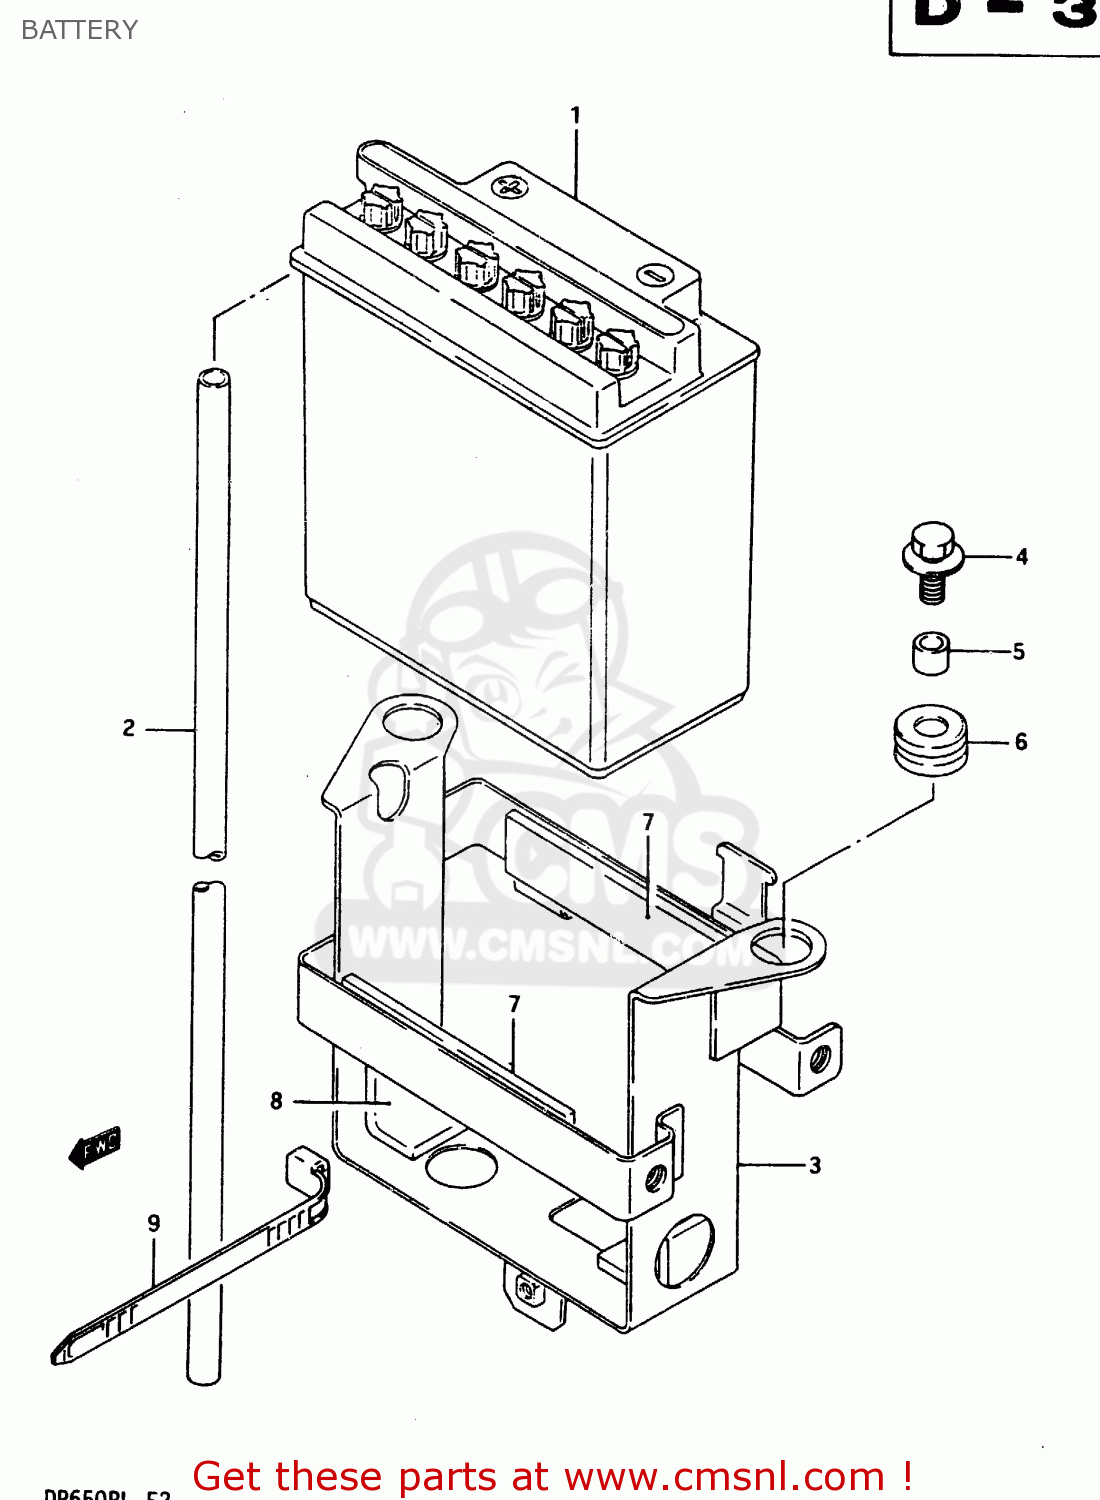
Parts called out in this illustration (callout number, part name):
1	BATTERY ASSEMBLY (12V)
2	HOSE,BATTERY EXHAUST
3	HOLDER,BATTERY
4	BOLT
5	SPACER(6.1X9X7.5)
6	CUSHION
7	PROTECTOR,20X9
8	PROTECTOR(30X80X2)
9	CLAMP(L:125)
